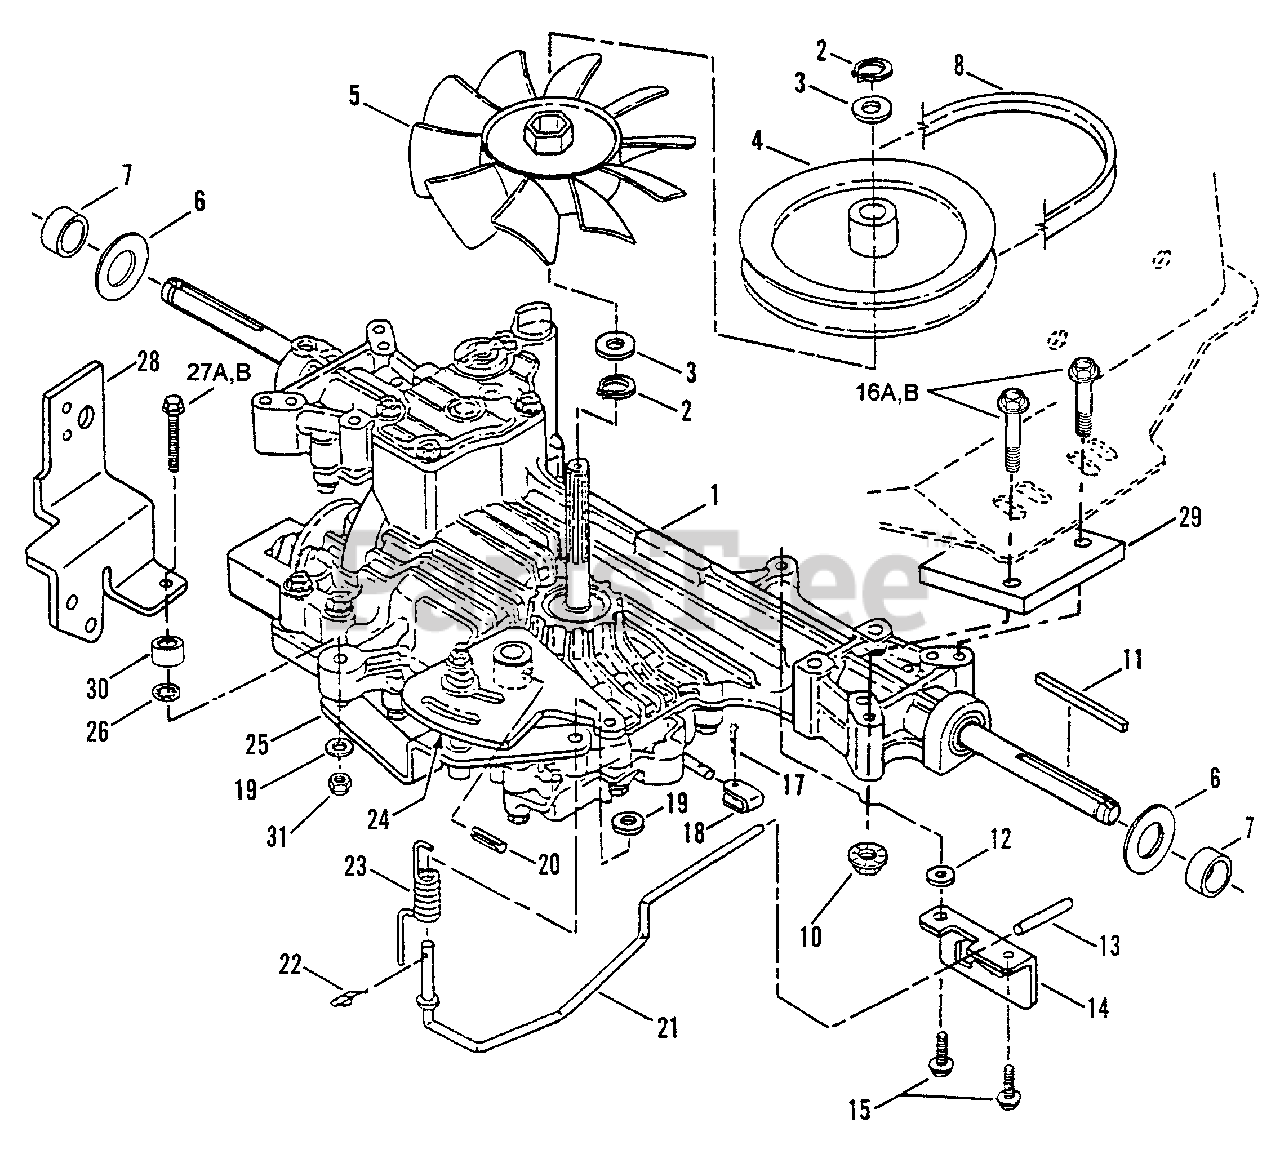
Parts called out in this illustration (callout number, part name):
1	TRANSAXLE, Hydro Drive, Tuff-Torq Model K50
2	RING, External Retaining 13.8mm
3	WASHER, Fan/Hub
4	PULLEY, Drive, 4.5" O.D. Splinned Hub
5	FAN
6	WASHER, Flat, 1/8 x 25/32 I.D. x 1-1/2" O.D.
8	BELT, Traction Drive
10	NUT, 5/16-18 Hex Flange Lock Grade 5
11	KEY, Square, 3/16 x 3/16 x 2-1/2"
12	WASHER, Flat, 3/4" O.D.
13	GRIP, Roll Release
14	DETENT, Roll Release
15	SCREW, 3/8-16 x 1-3/4" Self-Tapping
16A	BOLT, 5/16-18 x 2-1/4" Hex Flange Lock Grade 2
16B	SCREW, 5/16-18 x 2-3/4, Grade 5
17	COTTER-PIN, 5/32 x 1"
18	LINK, Roll Release
19	WASHER, 11/32 x 11/16 x 1/16
20	ROLL-PIN, 6mm x 32mm
21	WIREFORM, Roll Release
22	COTTER-PIN, 5/16 Self-Locking
23	SPRING, Torsion (Roll Release)
24	ASSEMBLY, Speed Control/Friction
25	SUPPORT, Friction Stud Assembly
26	RETAINER, 5/16 Bolt
27A	BOLT, 5/16-18 x 2" Hex Flange Lock, Grade 5
27B	BOLT, 5/16-18 x 2-1/4, Hex Flange Lock
28	BRACKET, Spool
29	SPACER, Axle
30	SPACER, Torque, 3/8" Thick
31	NUT, 5/16-18 Hex Lock (Esna)
